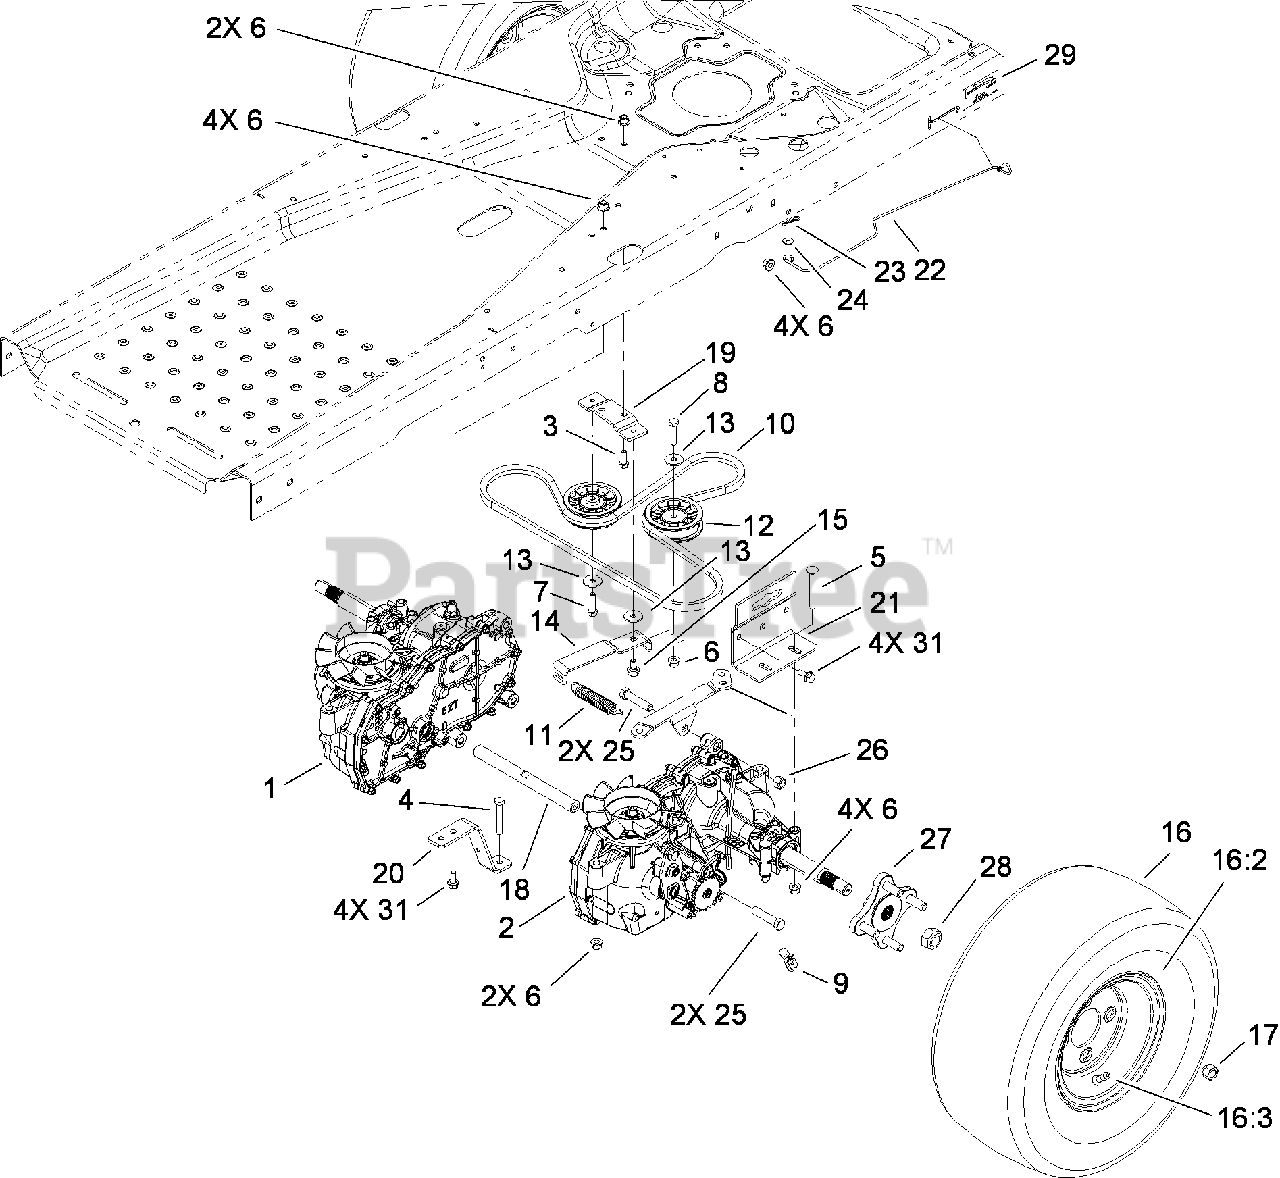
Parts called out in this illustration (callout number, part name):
1	HYDRO-RH
2	HYDRO-LH
3	SCREW-HH
4	SCREW-HH
5	SCREW-CARR
6	NUT-FLANGE, NI
7	SCREW-HH
8	SCREW-HH
9	CLIP-SPRING
11	SPRING-IDLER
12	PULLEY-IDLER
13	WASHER-PIVOT
14	ARM-IDLER
15	BOLT-SHOULDER
16	WHEEL AND TIRE ASM
16:2	Rim-Wheel
16:3	STEM-VALVE
17	NUT-LUG
18	SHAFT-CROSS
19	PLATE-PIVOT
20	STRAP-TORQUE
21	SUPPORT-HYDRO
22	ROD-BYPASS
23	PIN-COTTER, HAIR
24	WASHER-FLAT
25	SCREW-HH
26	NUT-LOCK, NI
29	DECAL-TRANSPORT, LH
31	SCREW-HHF
